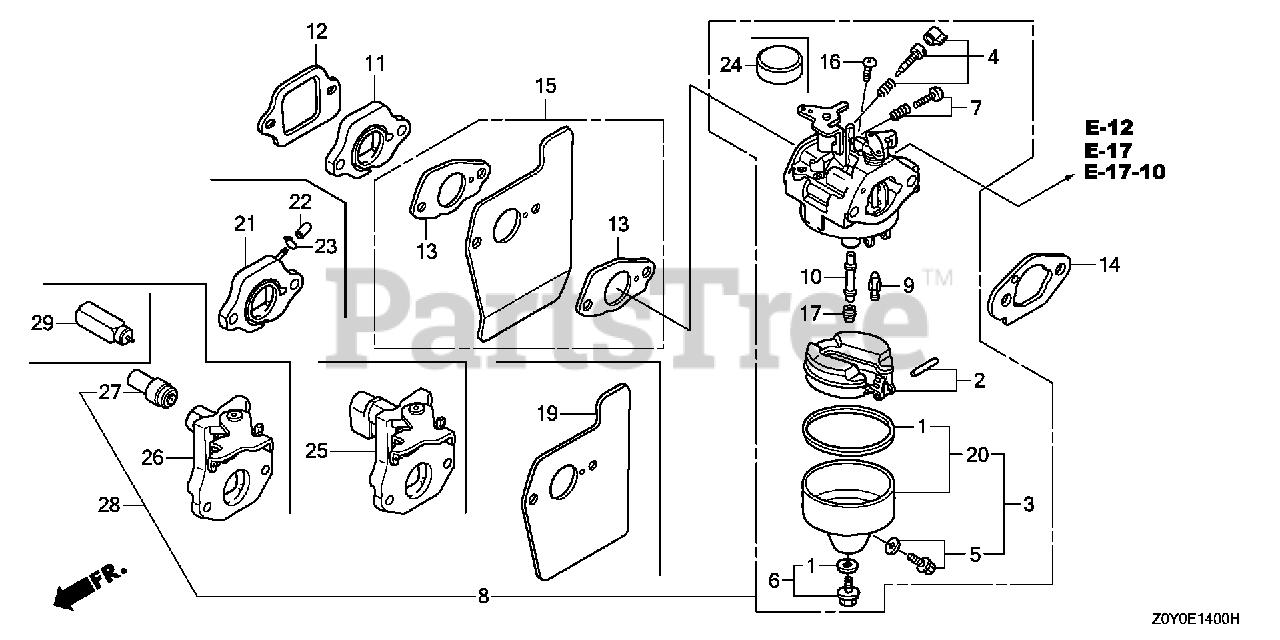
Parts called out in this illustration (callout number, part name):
1	GASKET SET
2	FLOAT SET
3	CHAMBER SET, FLOAT
4	SCREW SET (CARBURETOR NO.)
5	SCREW SET, DRAIN (Honda Code 1672187). (CARBURETOR NO.)
6	SCREW SET
7	SCREW SET (THROTTLE STOP) (CARBURETOR NO.)
8	CARBURETOR ASSY. (BB62J B)
9	VALVE, FLOAT (Honda Code 5580212). (CARBURETOR NO.)
9	VALVE, FLOAT (Honda Code 7934714). (CARBURETOR NO.)
10	NOZZLE, MAIN (CARBURETOR NO.)
11	INSULATOR, CARBURETOR
12	GASKET, INSULATOR
13	GASKET, CARBURETOR
14	GASKET, CARBURETOR (Honda Code 5580253). (CHOKE SIDE)
15	GUIDE, AIR
16	SCREW, PAN (5X6)
17	JET, MAIN (#65) Use up to Engine SN BB30A D.
17	JET, MAIN (#68) Use up to Engine SN BB30A D.
17	JET, MAIN (#70) Use up to Engine SN BB30A D.
